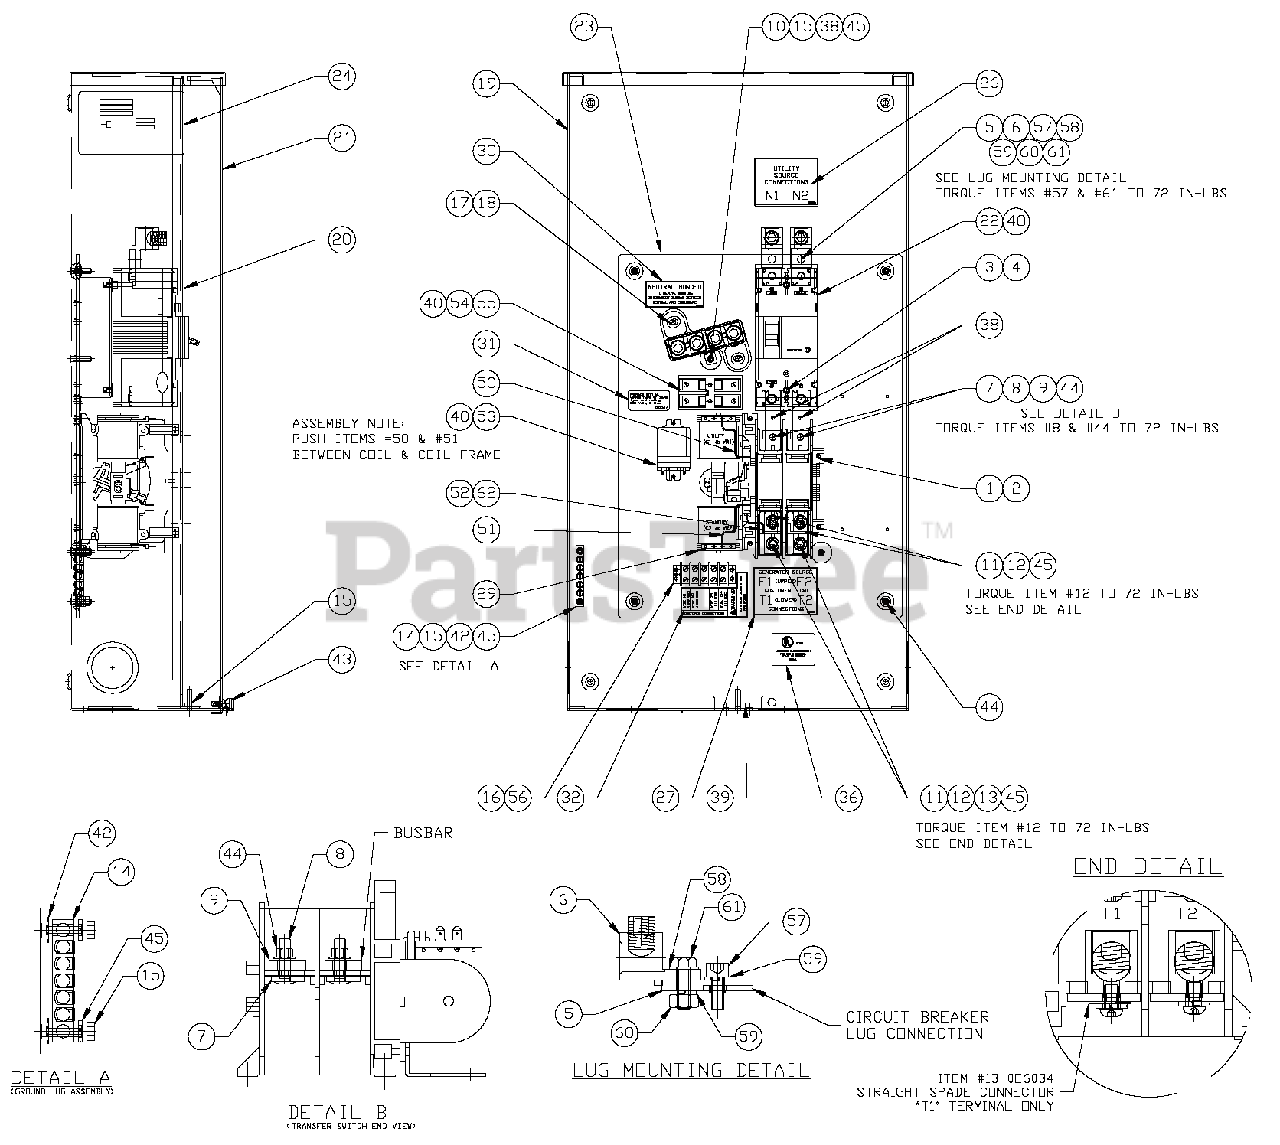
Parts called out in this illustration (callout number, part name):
1	TRANSFER SW. HSB 200A 2P 250V
2	SCREW HHTT M5-0.8 X 10 BP
3	CIRCUIT BREAKER, 200A 2-POLE
4	SCREW RHM #8-32 X 3-1/4
5	BUSBAR, 200A LUG ADAPTER
6	LUG 300 MCM-6STR
7	SPACER 200 AMP TRANSFER
8	BOLT CARR 1/4-20 X 1"
9	BUSBAR, 200A TRANSFER SW N1,N2
10	BUSBAR, NEUTRAL BLOCK
11	LUG SOLDERLESS 250-#6 AL/CU
12	SCREW BHSC 1/4-20 X 3/8
13	STRAIGHT SPADE CONNECTOR
14	GROUND BAR (5) 2-14 AWG CONN
15	NUT HEX 1/4-20 SS
16	RIVET, POP .156 X .67
17	ASSY-NEUT BLK 200-400A W/TAP
18	SCREW HHTT M6-1.0 X 12 MM
19	ENCLOSURE, 200A SE XFER SW
20	COVER, INSIDE 200A DUAL BREAKER
21	COVER, TRANSFER SWITCH
22	CB RISER BRACKET 200A GENERAC
24	DECAL SWITCH DATA
26	DECAL, UTILITY SOURCE CONN
27	DECAL, GENERATOR/CUSTOMER
29	DECAL, TRANSFER SWITCH INFO
30	DECAL, NEUTRAL CONNECTION
31	DECAL, FUSE REPLACEMENT
32	DECAL, TERMINAL STRIP
36	DECAL, UL LIST HSB
38	SCREW HHTT #8-32 X 1/4 CZ
39	NUT TRIC 1/4-20 X .525
40	SCREW HHTT M4-0.7 X 10 BP
42	WASHER SHAKEPROOF EXT 1/4 STL
43	THUMB SCREW 1/4-20x1/2
44	NUT HEX FL WHIZ 1/4-20
45	WASHER LOCK M6-1/4
52	WIRE-E1
53	RELAY PNL 12VDC DPDT
54	FUSEBLOCK 30A 600V 2 POLE
55	FUSE 5A X BUSS HLDR73591
56	BLOCK TERM 20A 5 X 6 X 1100V
57	SCREW SHC M8-1.25 X 20 G8
58	WASHER FLAT 5/16-M8 ZINC
59	WASHER LOCK M8-5/16
60	NUT HEX M8-1.25 G8 CLEAR ZINC
61	SCREW HHC M8-1.25 X 25 C8.8
62	90 DEGREE UP SPADE CONNECTOR
